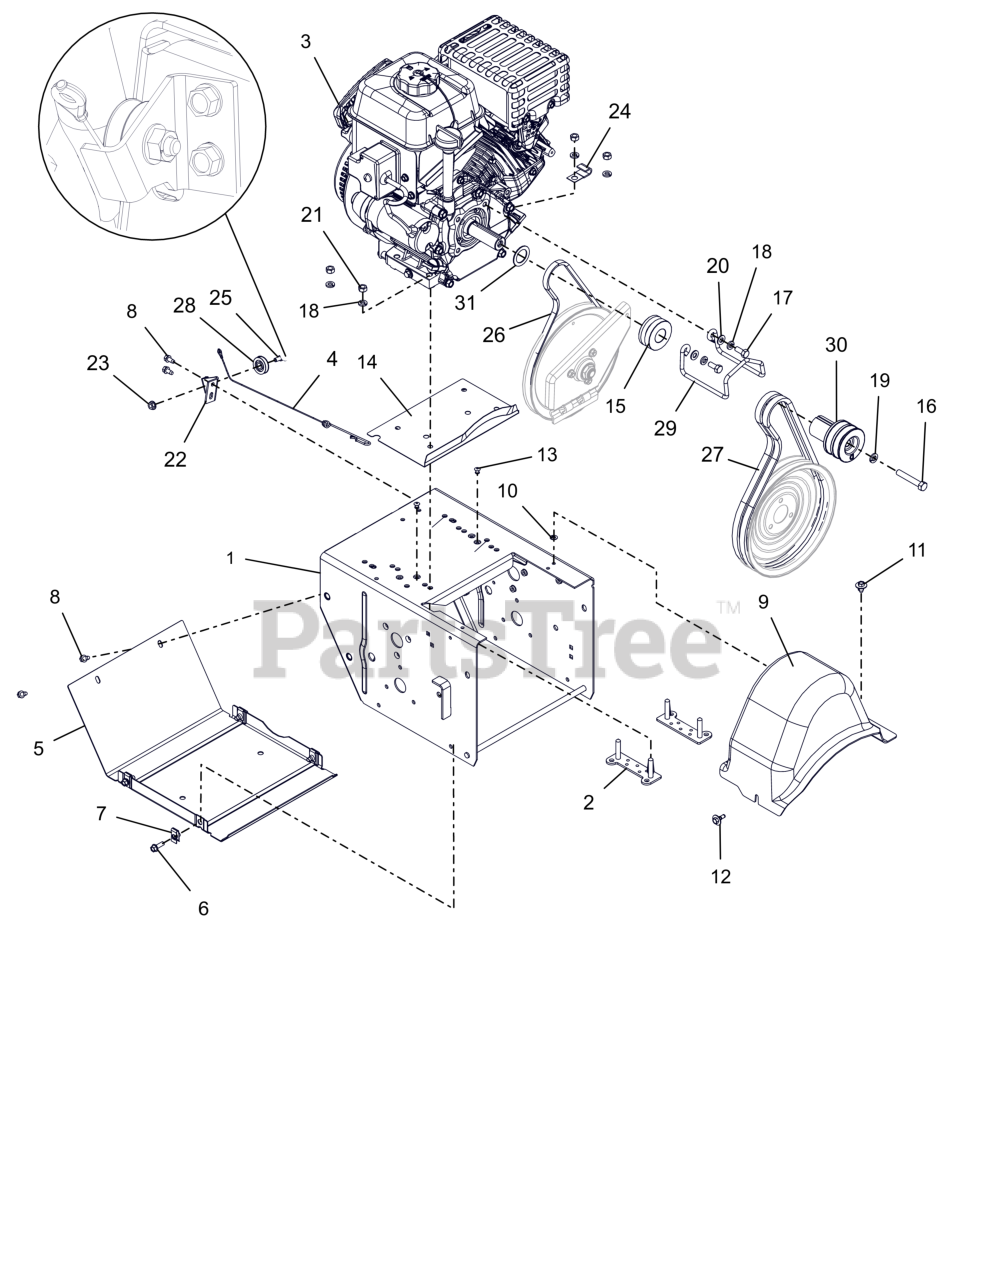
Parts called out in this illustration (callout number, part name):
1	FRAME, MAIN-DELUXE(WELDMENT)
2	STRAP, BOLT - SMALL ENGINE
3	ENGINE, ARIENS AX254 240V/60W
4	CABLE, LOWER TRACTION,SS & PRO
5	COVER, BOTTOM
6	BLT, HWH .25-20X.75 G5 ZCC
7	NUT-RTNR .25-20X.56
8	SCR-TAP .25-20X.50 HWH ZCC
9	COVER, BELT-SMALL
10	NUT-PUSH .25X.50 O.D.
11	SCR, TAP .25-20X.50 LG HWH ZCC
12	SCR-TAP .25-20X.5 CAPTIVE
13	RVT, POP .1875 ZCC
14	BAFFLE, WATER-SMALL
15	SHEAVE, TRACTION (KEYLESS)
16	BLT, HEX .38-24X2.25 G5 ZCC
17	BLT, HEX .31-24X.750 G5 ZCC
18	WSHR, LK-HVY .312X.097 ZCC
19	WSHR,LK-REG .375X.094 ZCC
20	WSHR,FLT .344X.688X.065 ZCC
21	NUT, HEX .312-18 ZCC
22	BRACKET, CABLE PULLEY
23	NUT-LK-TOP-FLG .250-20 GF ZCC
24	J-CLAMP
25	BOLT, SHLDR -.375 X .375 X .25-20
26	V-BELT, 3L-WRAPPED
27	V-BELT, HA-RAW EDGE (SET)
28	PULLEY, CABLE
29	FINGER, BELT
30	SHEAVE,ATTACHMENT-STD 2 GRV
31	WSHR, FLT 1.010X1.505X.062 ZCC
